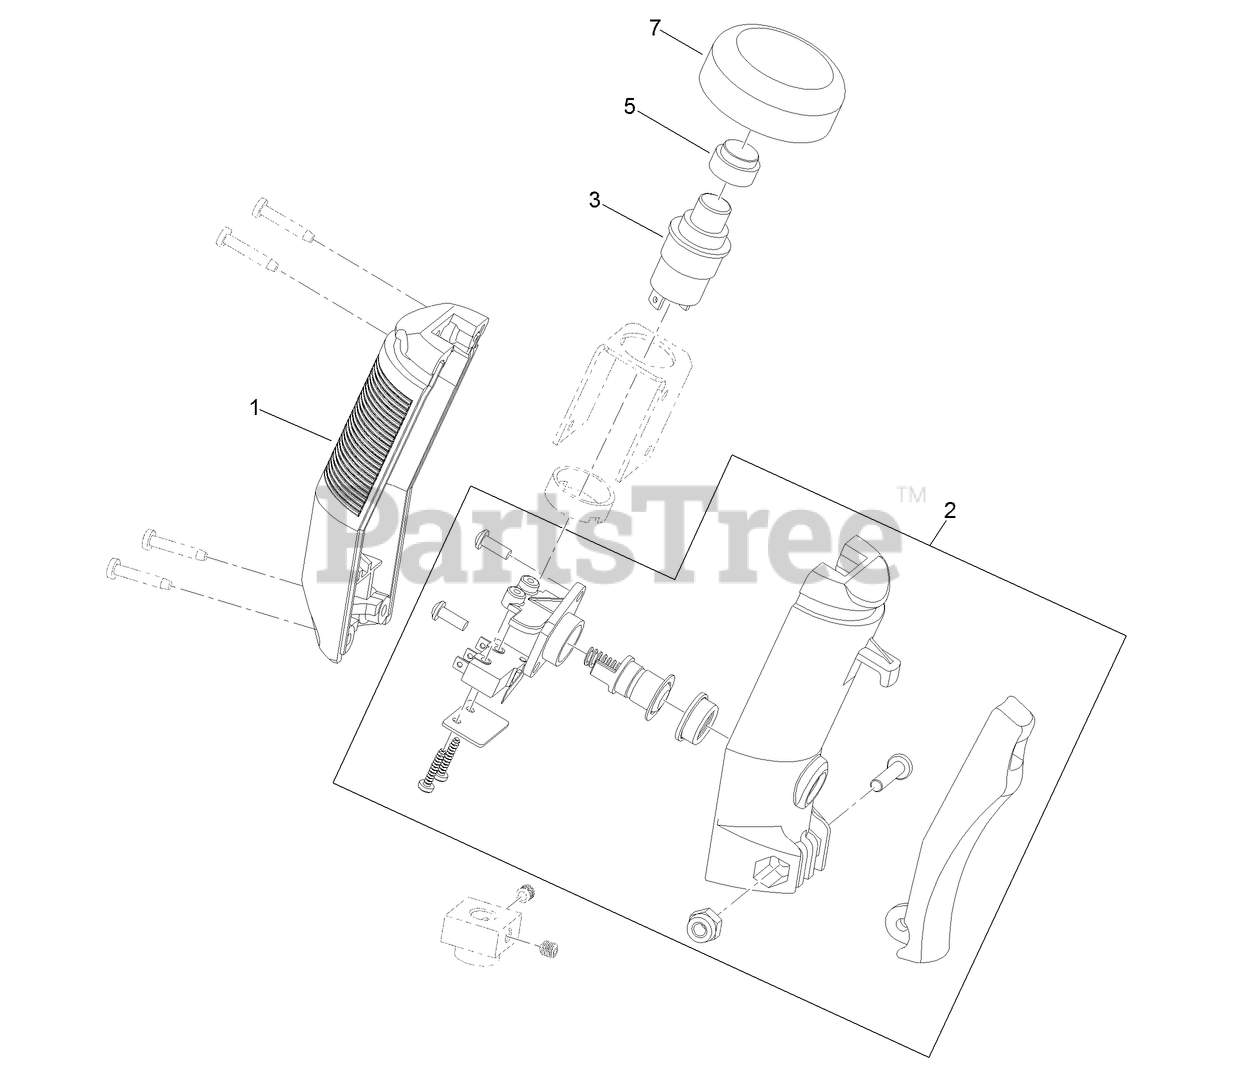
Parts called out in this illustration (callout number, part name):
1	HALVE-HANDLE
2	SWTICH KIT
3	BUTTON-PUSH, TOP
5	BUTTON-ACTUATOR
7	BOOT-BUTTON
